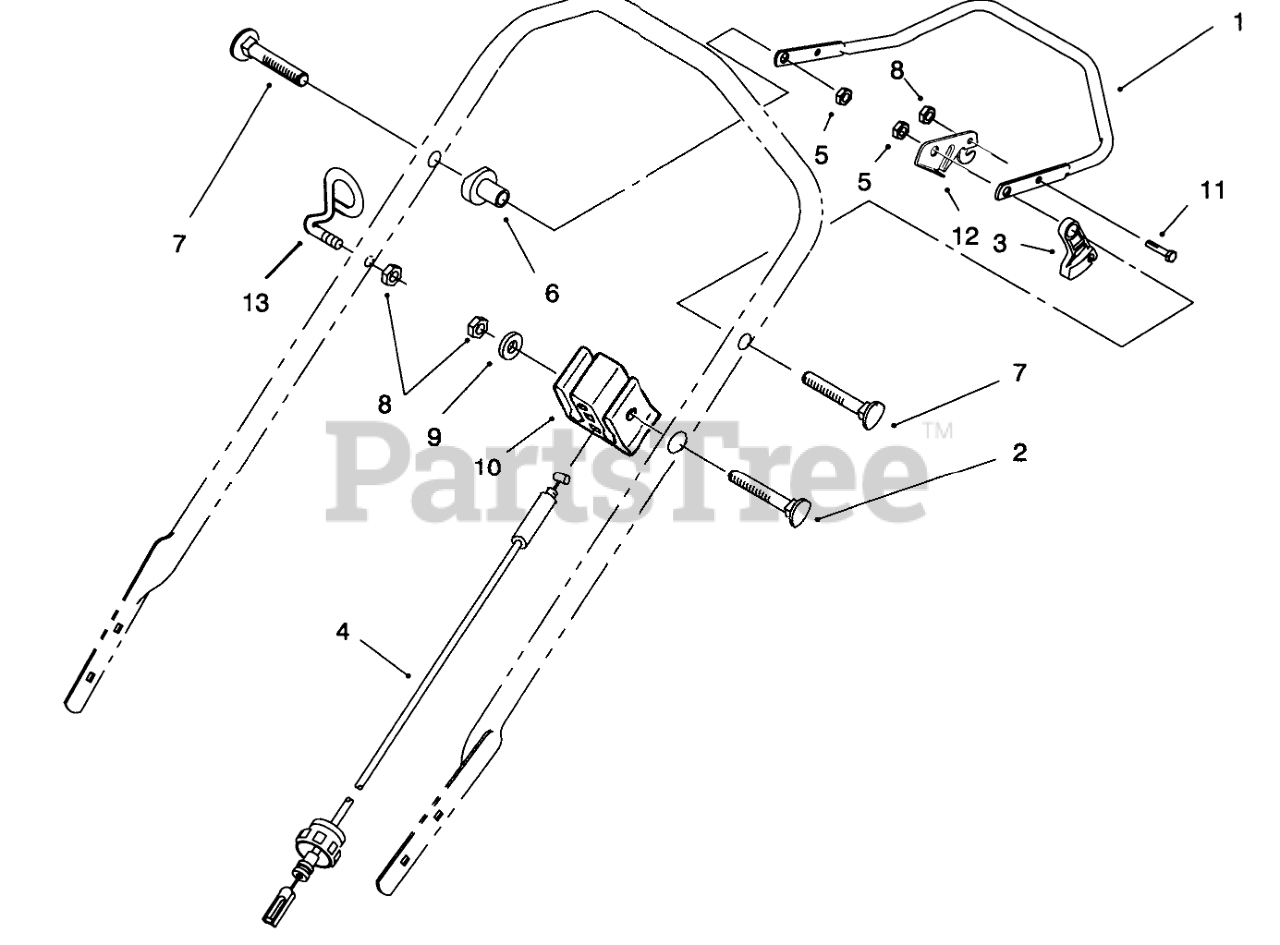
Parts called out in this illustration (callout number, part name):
1	Bar-Control
2	HANDLE SCREW
3	LEVER-TRACTION
4	CABLE-TRACTION
5	NUT-LOCK, NI
6	SPACER-SUPPORT
7	5/16-18 X 2 HNDLE SCREW
8	NUT-LOCK, NI
9	WASHER-FLAT
10	SUPPORT-CABLE
11	SCREW-HH
12	LEVER-CONTROL
13	ROPE GUIDE
